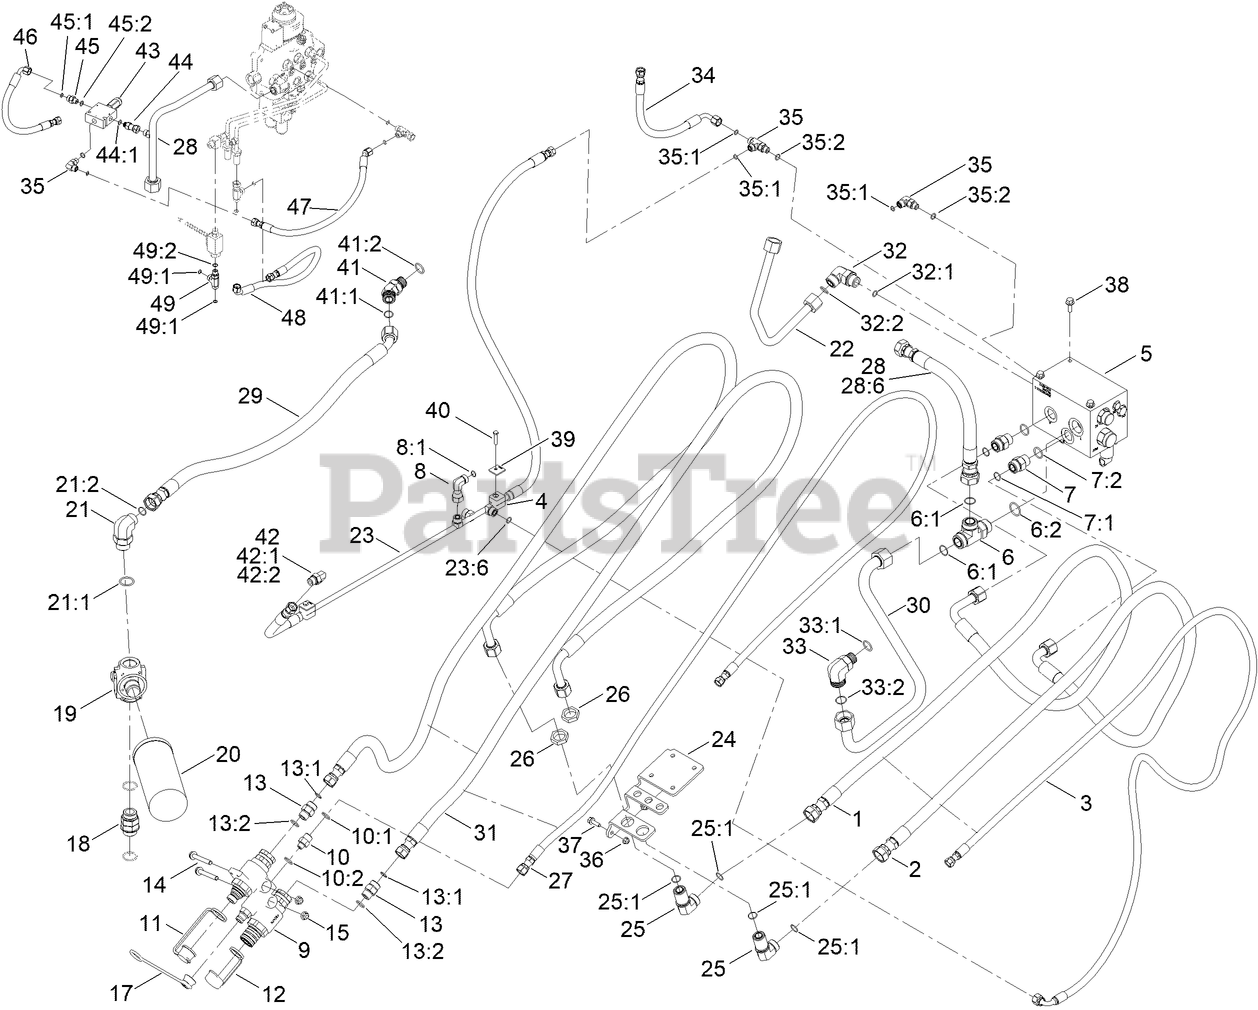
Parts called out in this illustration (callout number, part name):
1	HYD HOSE ASM
2	HYD HOSE ASM
3	HYD HOSE ASM
4	CLAMP-TUBE
5	AUX MANIFOLD ASM
6	FITTING-TEE
6:1	O-RING
6:2	O-RING
7	FITTING-HYD, STRAIGHT
7:1	O-RING
7:2	O-RING
8	FITTING-HYD
8:1	O-RING
9	MANIFOLD-QDC
10	FITTING-STRAIGHT
10:1	O-RING
10:2	O-RING
11	CAP-DUST, NIPPLE
12	CAP-DUST, COUPLER
13	FITTING-STRAIGHT
13:1	O-RING
13:2	O-RING
14	SCREW-HFH
15	NUT-HF, NI
17	CAP-DUST, NIPPLE
18	FITTING-STRAIGHT
19	HEAD-FILTER
20	ELEMENT-FILTER
21	FITTING-ELBOW 90
21:1	O-RING
21:2	O-RING
22	HYD TUBE ASM
23	HYD TUBE ASM
23:6	O-RING
24	MOUNT-CARRIER
25	FITTING-ELBOW 90
25:1	O-RING
26	NUT-BULKHEAD
27	HYD HOSE ASM
28	HYD TUBE ASM
28:6	O-RING
29	HYD HOSE ASM
30	HYDRAULIC TUBE ASM
31	HYD HOSE ASM
32	FITTING-ELBOW-90
32:1	O-RING
32:2	O-RING
33	FITTING-ELBOW 90
33:1	O-RING
33:2	O-RING
34	HYD HOSE ASM
35	FITTING-ELBOW, 90 DEG
35	FITTING-TEE
35:1	O-RING
35:2	O-RING
36	NUT-HF, NI
37	SCREW-HHF
38	SCREW-HHF
39	PLATE-CLAMP,TUBE
40	SCREW-HH
41	FITTING-45 DEG
41:1	O-RING
41:2	O-RING
42	FITTING-ELBOW, 90 DEG
42:1	O-RING
42:2	O-RING
43	VALVE-SEQUENCE
44	CONNECTOR-SWIVEL, STRAIGHT
44:1	O-RING
45	FITTING-STRAIGHT
45:1	O-RING
45:2	O-RING
46	HOSE ASM
47	HOSE-HYD
48	HOSE-HYD
49	FITTING-TEE
49:1	O-RING
49:2	O-RING
